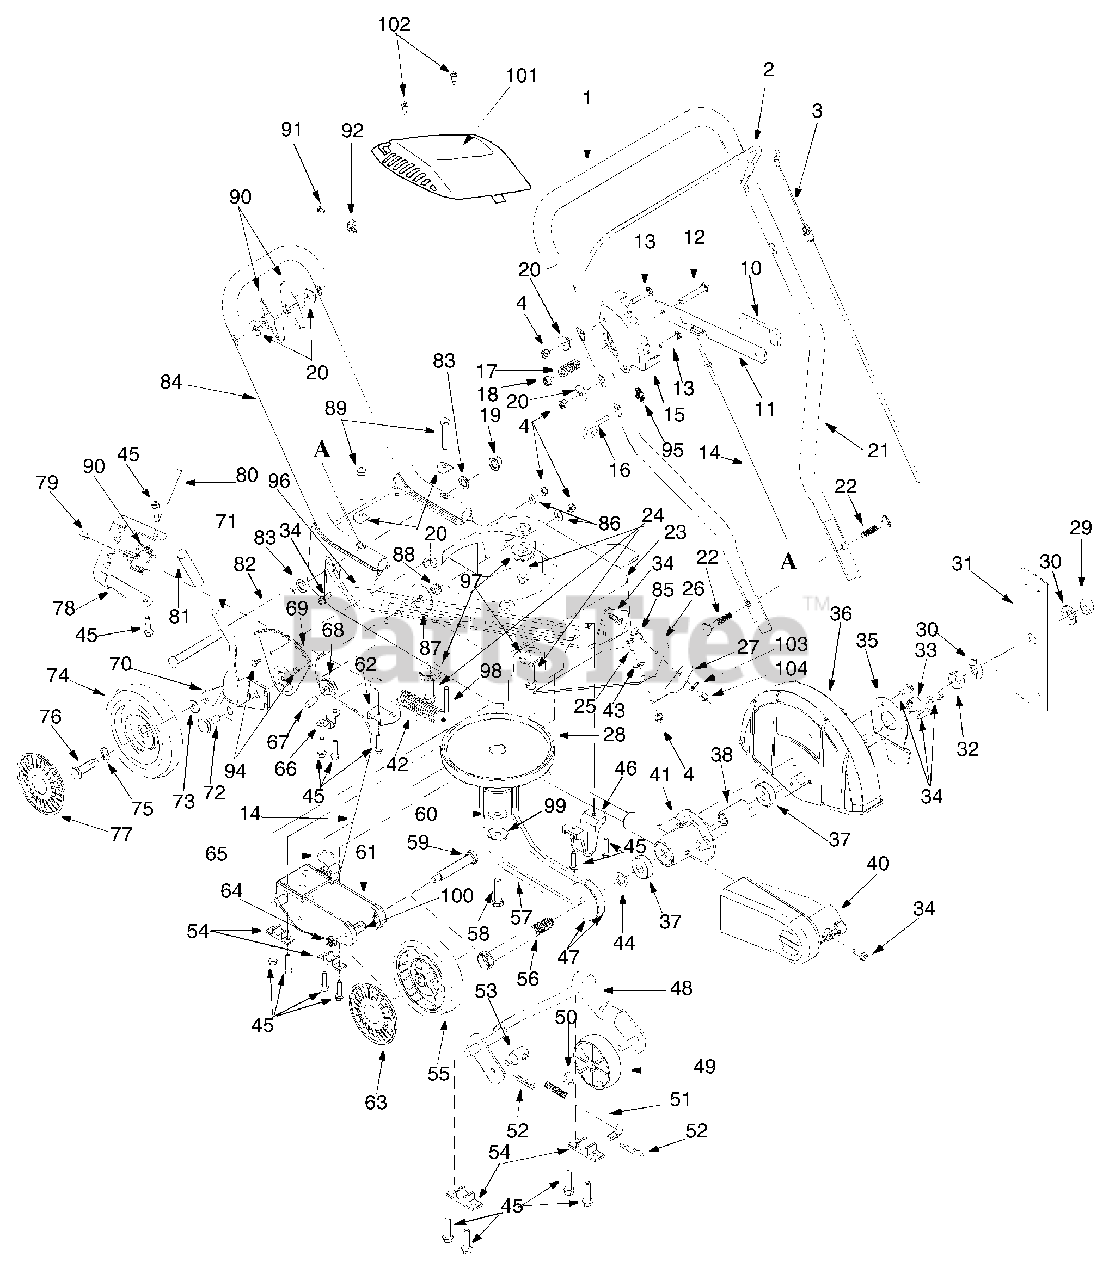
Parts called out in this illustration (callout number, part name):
1	Foam Grip
3	Control Cable 34" B&S
4	Hex Lock Nut 1/4-20
10	Depth Lever Grip
12	Hex Screw 5/16-18 x 2.0 Lg.
13	Thrust Screw 1/4-20 x 1.5
14	Depth Cable
15	Depth Bracket
16	Eye Bolt 1/4-20
17	Compression Spring .550 O.D. x 1.3
18	Hex Lock Nut 5/16-18
20	Washer .320 ID x .93 O.D.
23	Edger Base Ass'y
24	Tapp Screw w/Hex Lock Wash 3/8-16
25	Hex Screw 1/4-20 x .50 Lg.
26	Discharge Shield Deflector
27	Deflector Keeper
28	Engine Pulley
29	Hex Jam Nut 5/8-18
30	Bell Washer .63 I.D. x 1.25 O.D. x .18
32	Hex Jam Nut 5/8-18
33	Spacer .628 x .875 x .545 Lg.
34	Hx Scr. w/Wash.: TT: 1/4-20 x .750 Lg.
37	Ball Bearing .62 I.D. x 1.38 O.D. x .4
38	Spacer .628 x .875 x 1.818 Lg.
40	Belt Guard
41	Spindle w/Insert
42	Compression Spring
43	Flat Washer .283 I.D x .75 O.D. x .030
44	Flat Washer .635 I.D. x .93 O.D. x .06
45	Hex Screw w/Wash 1/4
46	Front Rod Handler
47	Pulley
51	Rod 5/16-24
52	Cotter Pin .072 x 1.12
53	Ferrule 5/16-24 x .312
54	Black Bushing .515 Dia x .62
55	Wheel 7 x 2
56	Hex Bolt 5/8-18 x 5.25 Lg.
57	V-Belt
58	Hex Screw: 3/8-24 x 1.50 Lg.
59	Shoulder Screw .500 x 2.62: 3/8-16
60	Flat Washer .38 OD x 1.38 OD
61	Front Wheel Brkt Ass'y.
62	Rear Rod Handler
63	Hubcap: Spoke w/Hole Beige
64	Jam Lock Nut 3/8-16
65	Torsion Spring
68	Cable Roller Pulley
69	Index Plate
70	Pivot Arm
71	Spring Lever
72	Shoulder Bolt .500 x .434 Lg.
73	Bell Wash. .401 ID.x .870 OD. x .063
74	Wheel 8 x 2
75	Wave Washer .510 I.D. x .750 O.D.
76	Shoulder Bolt .498 x 1.445: 3/8-16
77	Hubcap: Radial Spoke Beige
78	Tilt Bracket
79	Adj. Lever Ass'y
80	Pin 1/4 x 2.0" Lg.
81	Foam Grip
82	Curb Axle
83	Flat Wash. .531 I.D. x .875 O.D. x .06
86	Flat Wash. .285 ID x 1.25 OD x .06
87	Flat Wash. .406 ID x 1.92 OD x .06
88	Hex Lock Nut 3/8-16
89	Hex Screw 5/16-18 x 1.75 Lg.
90	Torsion Spring
90	Wing Knob Nut 5/16-18
91	Hex Scr. w/Wash. :T: #10-32 x .625 Lg.
92	Clamp B&S Throttle
94	Screw Std. 1/4-20 x .75 Lg.
95	Handle Knob
99	Bell Washer .396 ID x 1.14 OD
100	Spacer .520 ID x .860 Lg.
101	Engine Shroud
102	Screw #10-32 x .625
103	Lock Washer 1/4
104	Hex Nut 1/4-20
